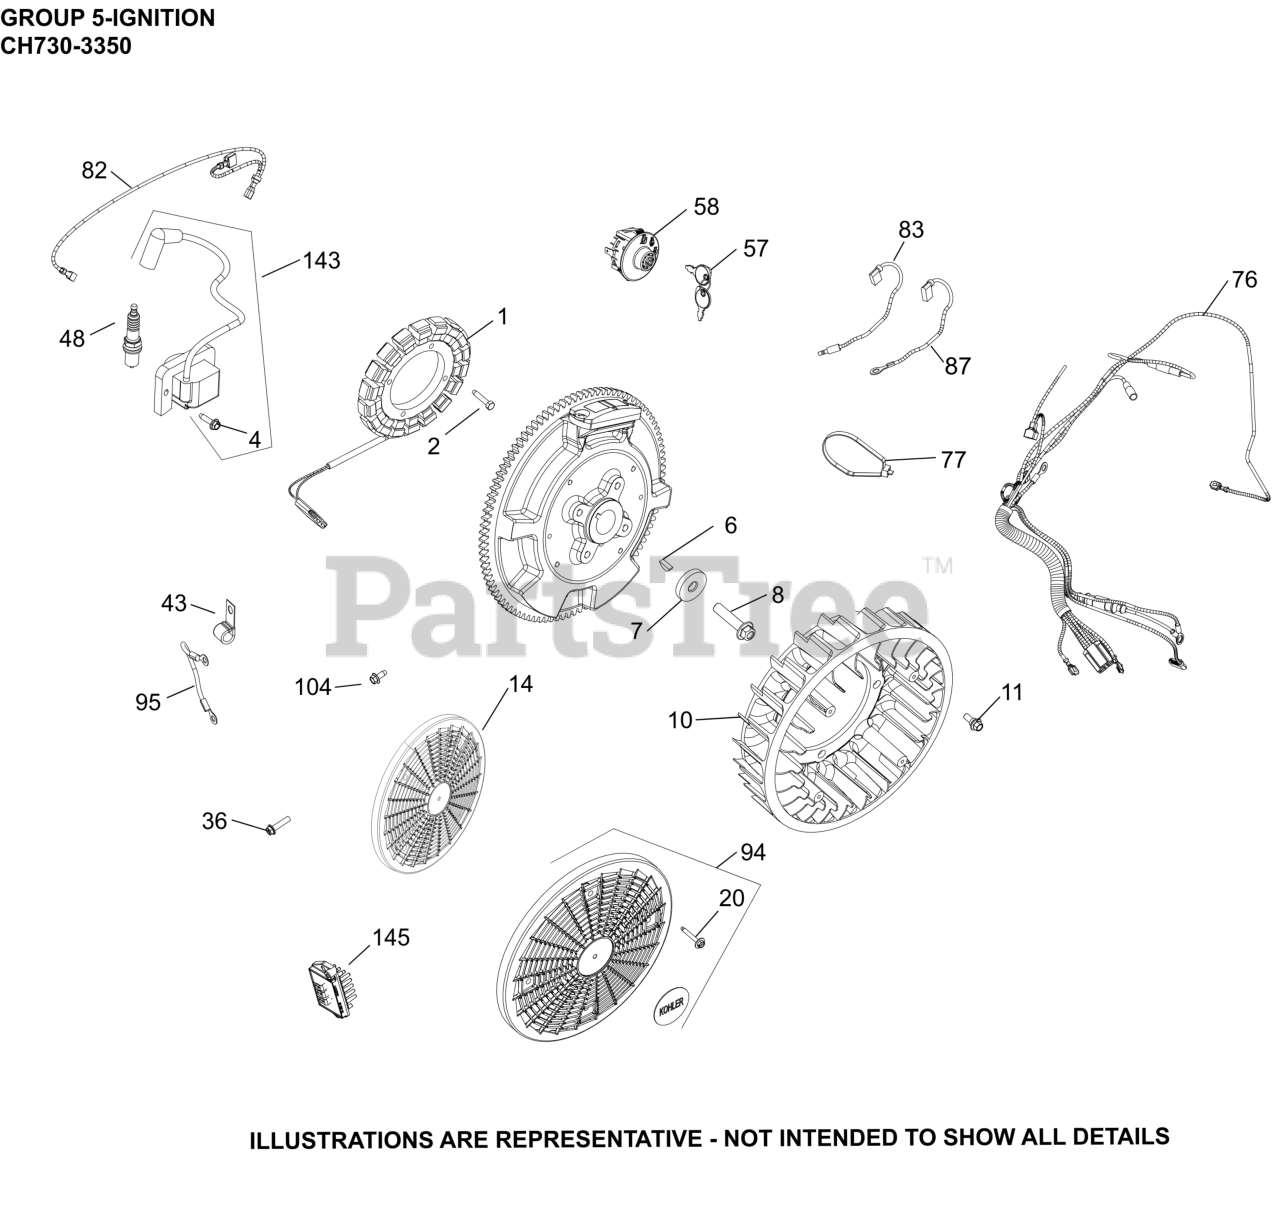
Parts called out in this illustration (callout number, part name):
1	KIT, 25 AMP STATOR ASSY.
2	SCREW, THREAD FORMING
4	SCREW, THREAD FORMING
6	KEY, 3/16" X 5/8"
7	WASHER, FLAT
8	SCREW, HEX FLANGE
10	FAN-USE 24 755 253-S
11	BOLT, SHOULDER
14	SCREEN, GRASS
20	SCREW, FLG SEMS M4x.7x25
36	SCREW, HEX FLANGE HI-LO
43	CLIP, CABLE
48	PLUG, SPARK (PRO SERIES)
57	KEY, SET OF 2
58	KIT, KEY SWITCH (SNAP-IN)
76	HARNESS, WIRING ASSEMBLY
82	LEAD, DUPLEX
83	LEAD, OIL SENTRY
87	LEAD, 20/25 AMP B+
94	KIT GRASS SCREEN
104	SCREW, THREAD FORMING
143	KIT IGNITION MODULE
145	REGULATOR, RECTIFIER (20-30AMP,FW W/OVP)
NI	FLYWHEEL ASSEMBLY (CV/CH670 & 730)
